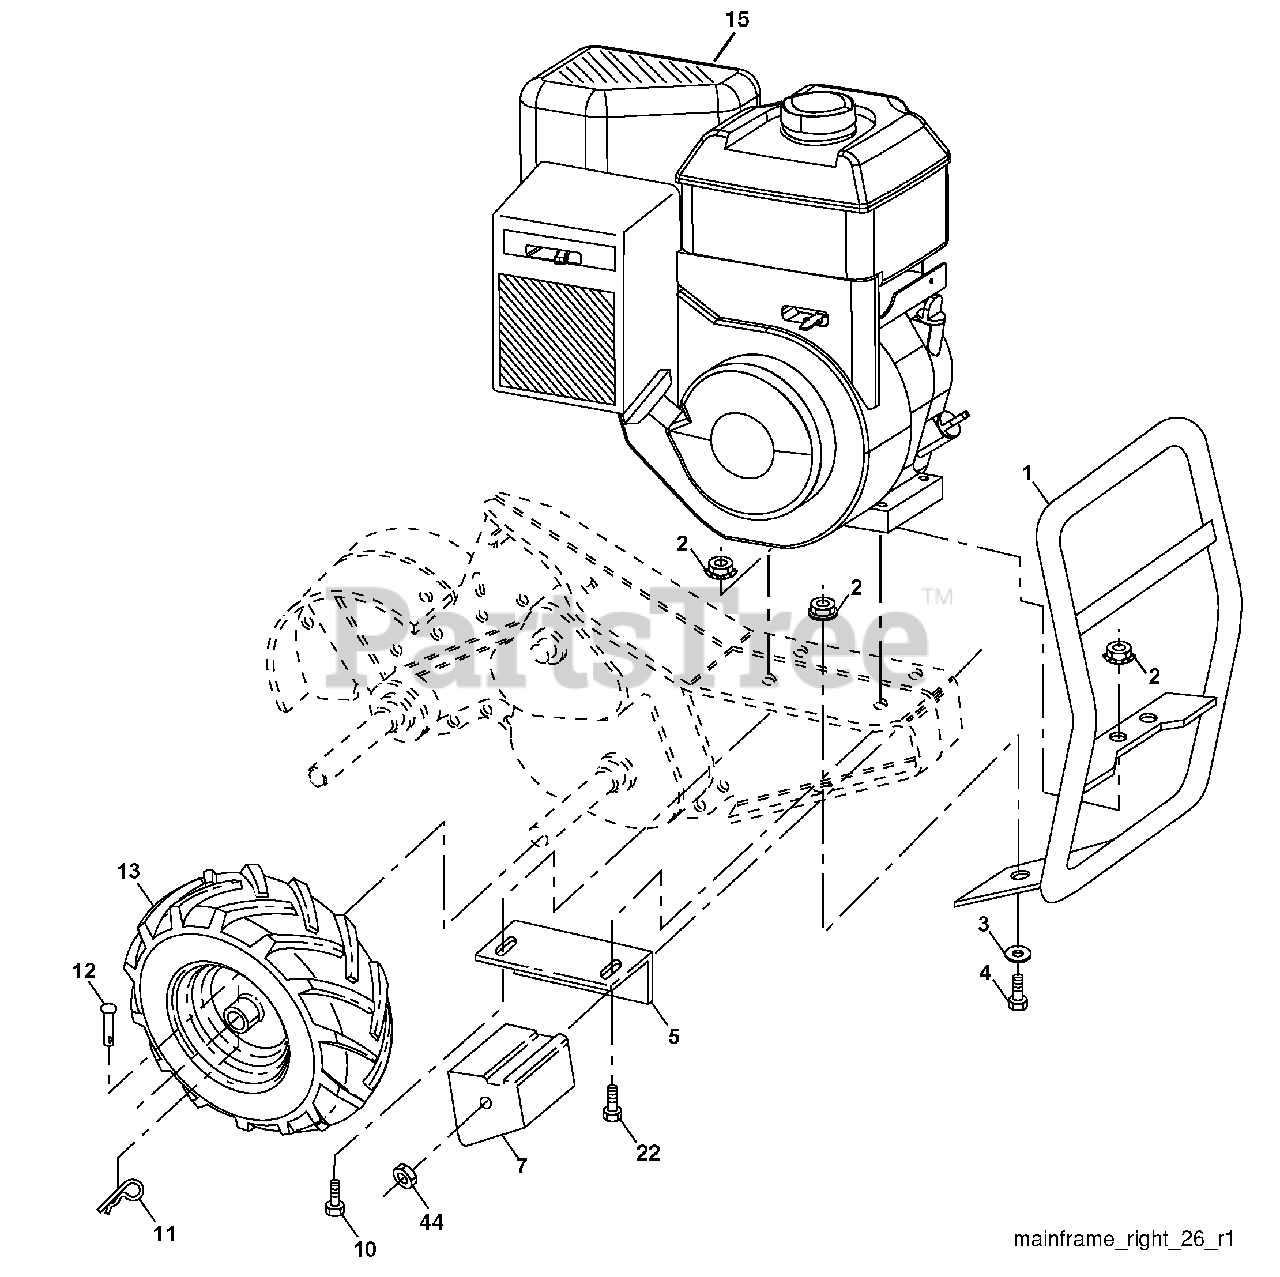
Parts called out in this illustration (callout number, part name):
2	Locknut, Hex, Flange 5/16-18
3	Washer 11/32 x 11/16 x 16 Ga.
4	Bolt, Hex 5/16-18 x 3/4
5	Bracket, Reinforcement
7	Counter Weight, R.H.
10	Bolt, Hex 5/16-18 x 1-1/2
11	Clip, Hairpin
12	Rivet, Drilled
13	Tire
13	Rim
13	Tire Valve
22	Bolt, Hex 5/16-18 x 1-3/4
44	Nut, Keps, Hex 3/8-16 unc
